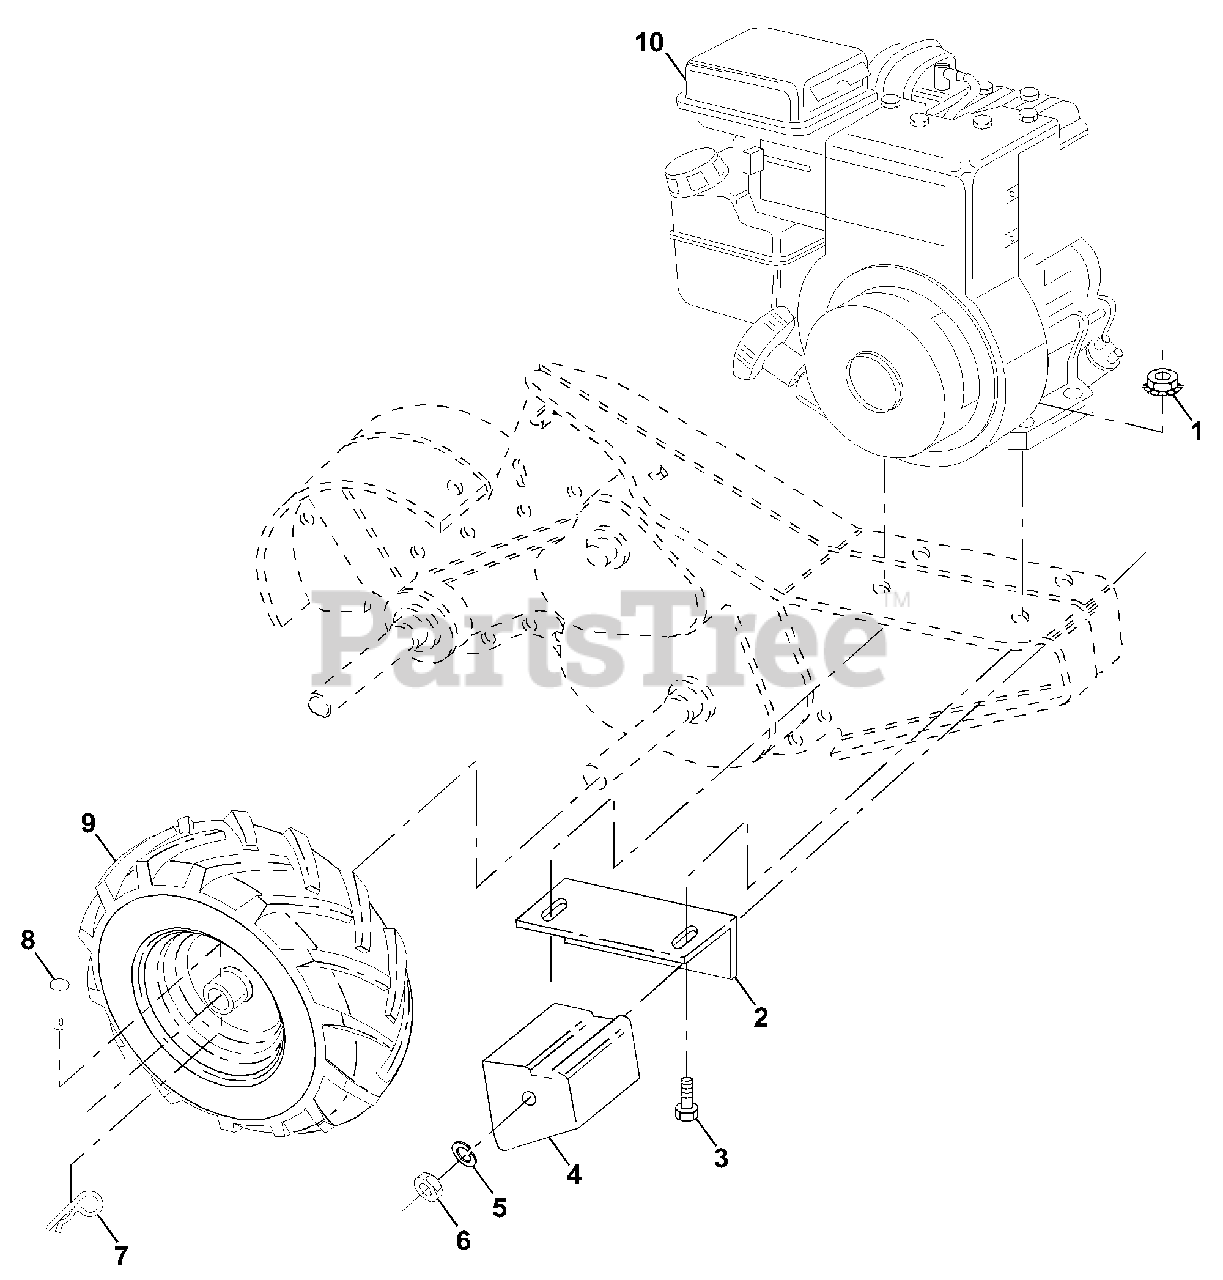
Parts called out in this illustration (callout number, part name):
1	Nut, Keps 5/16-18
2	Bracket, Reinforcement
3	Bolt, Hex 5/16-18 x 1-1/2
4	Counter Weight, R.H.
5	Washer, Lock 3/8
6	Nut, Hex 3/8-16
7	Clip, Hairpin
8	Rivet, Drilled
9	Tire Valve
10	Engine, Briggs & Stratton
